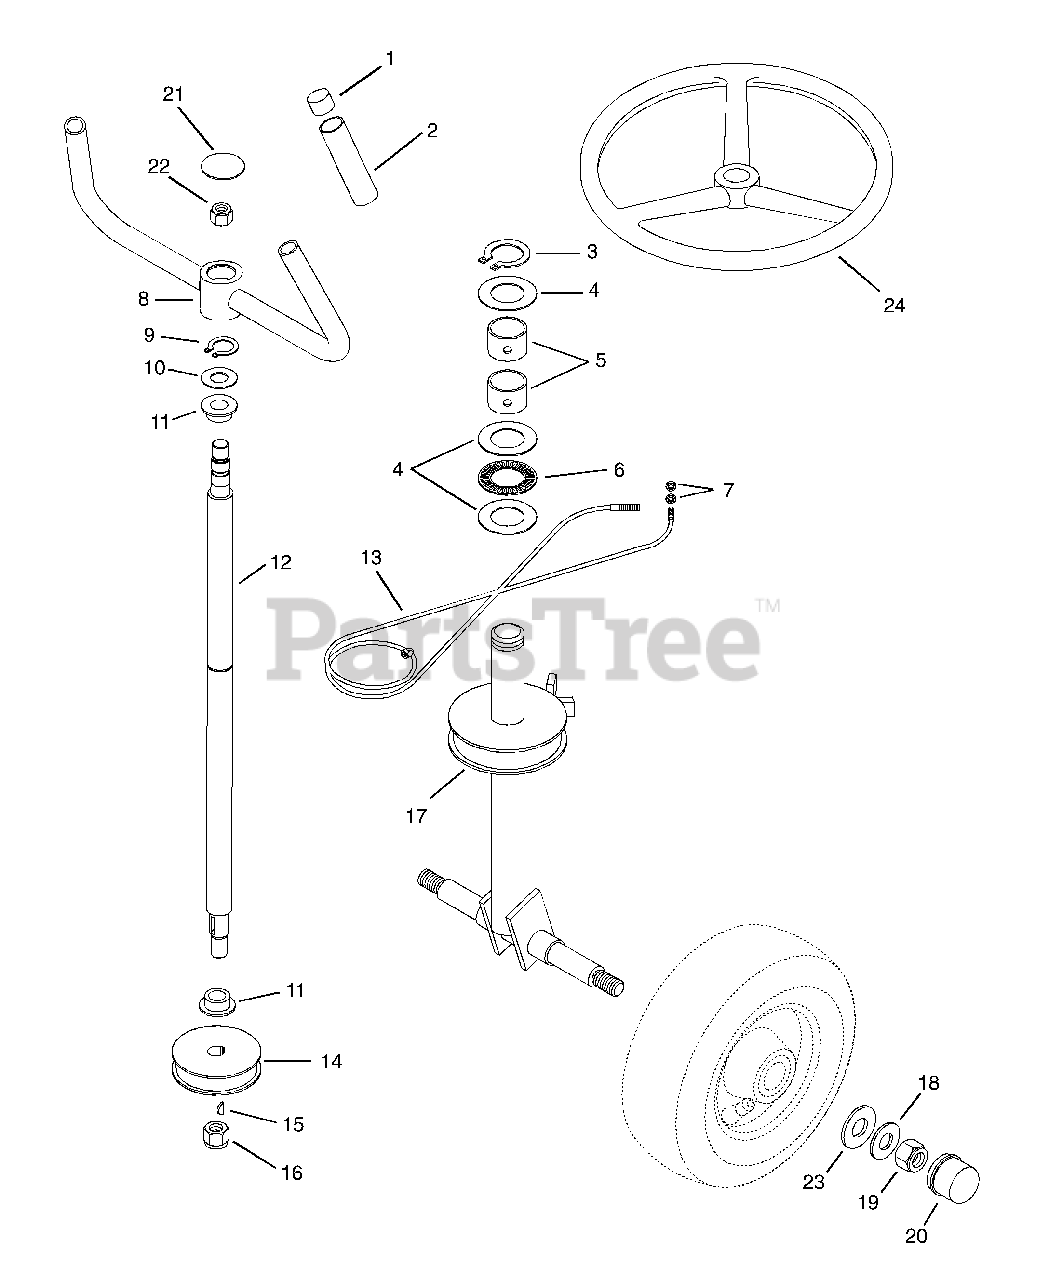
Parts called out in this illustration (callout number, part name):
1	Closure-Vinyl
2	Grip
3	Ring-Retaining-External 1.5 x 1.38
4	Washer-Thrust 1.502 x 2.18 x .063
5	Bearing 1.000 x 1.135 x 1.002
6	Bearing-Needle-Thrust 1.50 x 2.187 x .0781
7	Nut-Jam .312-18
8	Weldment, Handlebar
9	Ring-Retaining-External .906 x .078
10	Washer-Thrust 1.55 x 1.002 x .093
11	Bushing-Flange 1.020 x 1.385 x .75 x 1.75
12	Shaft-Steering
13	Cable-Steering
14	Pulley-Cable
15	Key-Woodruff 3/16 x 7/8
16	Nut-Locking 5/8-11
17	Weldment-Caster Wheel
18	Washer-Flat .812 x 1.469 x .134
19	Nut-Locking-Center .62 x -11
20	Cap-Dust
21	Closure-Vinyl
22	Nut-Hex .62-11
23	Washer-Hardened-Thrust 1.00 x 1.55 x .03
24	Steering Wheel
